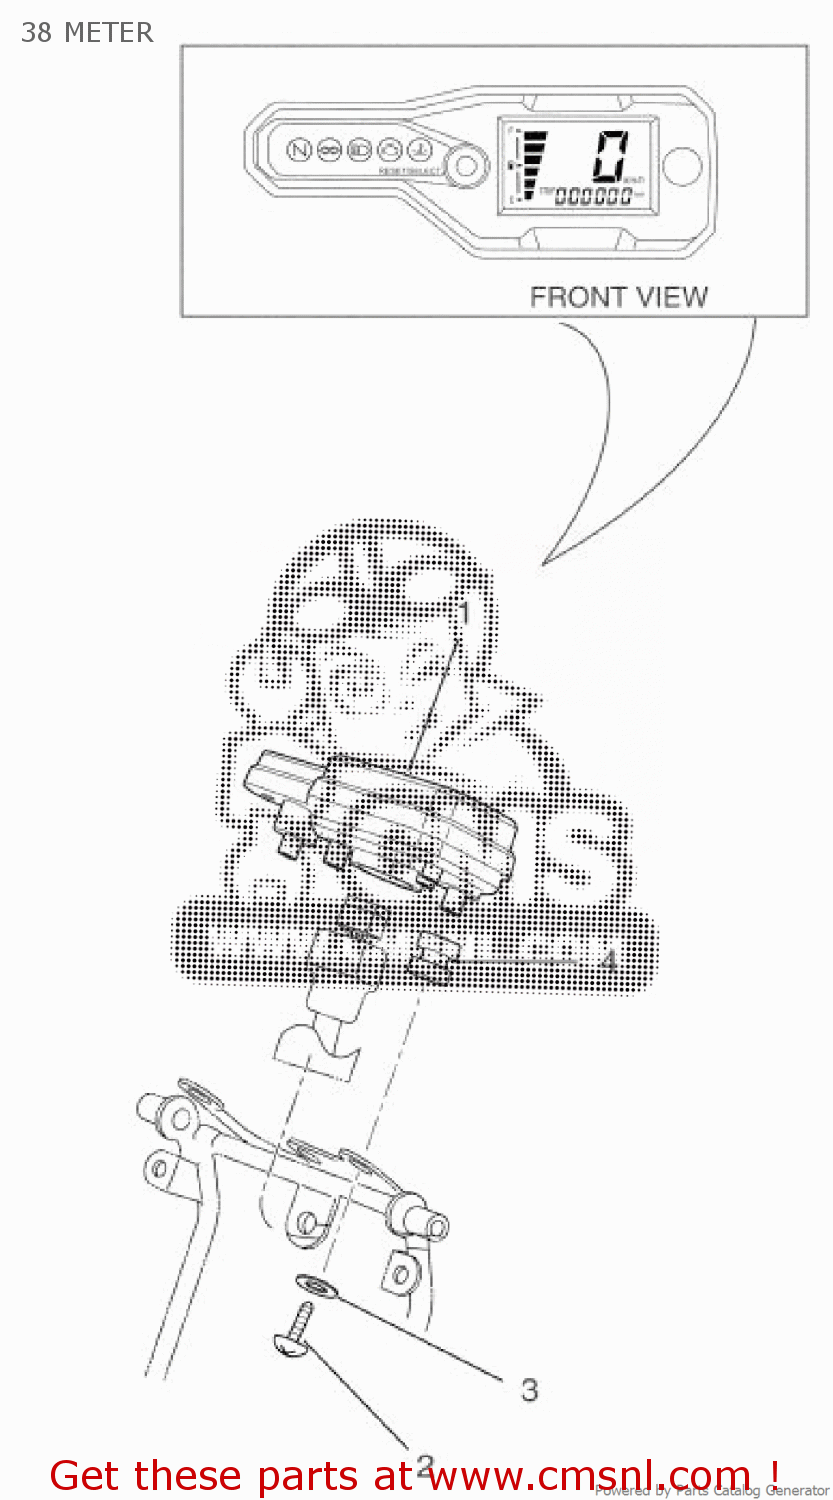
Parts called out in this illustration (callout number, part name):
1	METER ASSY
2	SCREW, TAPPING
3	WASHER, PLAIN(ZN)
4	GROMMET
